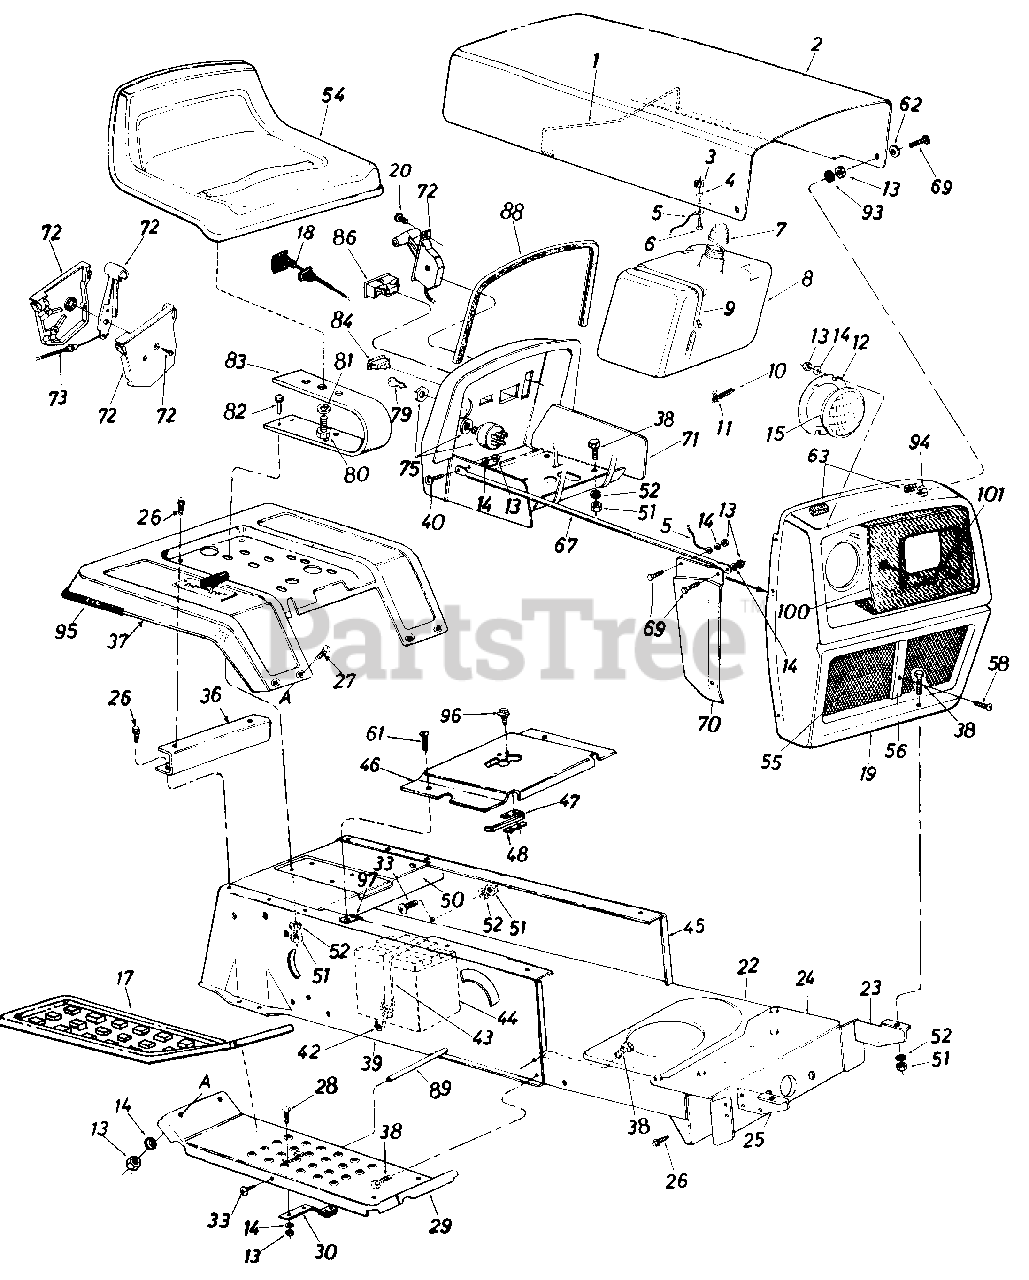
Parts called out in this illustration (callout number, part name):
1	Hood Spring
2	Hood
3	Hex Sems Nut #10-24 Thd.*
5	Hood Stop 7" Lg.
6	Truss Hd. Scr. #10-24 x 1/2"*
7	Fuel Cap Gauge
8	Fuel Tank
9	Tie Strap
10	Fuel Line
11	Hose Clamp
12	Headlight Retainer
13	Hex Nut 1/4-20 Thd.*
14	L-Wash. 1/4" I.D.*
15	Headlight
17	Foot Pad
18	Choke Control 29" Lg.
19	Grille Ass'y.
20	Truss Mach. AB-Tap Scr. #10 x .50" Lg.
22	Lower Frame
23	Grille Mount Brkt.-L.H.
24	Front Pivot Brkt.
25	Grille Mount Brkt.-R.H.
26	Hex Wash. Hd. AB-Tap Scr. 5/16 x .75" Lg.
27	Carriage Bolt 1/4-20 x .50"*
28	Carriage Bolt 1/4-20 x .62"*
29	Running Board
30	Blade Brake Ass'y.
33	Truss Mach. Scr. 5/16-18 x .75" Lg.*
36	Fender Mount Brace
37	Fender
38	Hex Bolt 5/16-18 x .75" Lg.*
39	R.H. Side Frame
40	Hex Bolt 1/4-20 x .62" Lg.*
42	Battery Strap Hook
43	Battery Hold Down Strap
44	12-V Battery
45	L.H. Side Frame
46	Shift Cover
47	Reverse Safety Switch
48	Insulator Nut Plate
50	Hitch Plate
51	Hex Nut 5/16-18 Thd.
52	L-Wash. 5/16" I.D.
54	Seat Ass'y.
55	Seat with Safety Switch
56	Moulding
58	Hex Wash. F-Tap Scr. #8 x .38" Lg.
61	Truss Mach. Tap Scr. #10 x .50" Lg.
62	Fl-Wash. .281 I.D. x .73 O.D.
63	Foam Strip 3/8 x 1-1/8 x 11/2
67	Grille Support Rod
69	Truss Hd. Scr. 1/4-20 x .75"*
70	R.H.-Grille Side Panel
71	Dash Panel Ass'y.
72	Throttle Control Box Ass y.
73	Throttle Control Wire
75	Ignition Switch
79	Ignition Key
80	Hex Bolt 1/2-13 x 1.0" Lg.
81	L-Wash. 1/2" I.D.
82	Hex Bolt 5/16-18 x 1.0"*
83	Seat Spring 5.5" High
84	Light Switch
86	Ammeter
88	Molding Strip 27" Lg.
89	Running Board Rod
93	Rubber Wash. 1/2" I.D. x 1.0 O.D. x .25"
94	Hex Sems Ins. L-Nut 1/4-20 Thd.
95	Trim Strip-81"
96	Hex Wash. Hd. AB-Tap Scr. #8 x .50" Lg.
97	Speed Nut #10Z
100	Bezel
101	Truss Scr. #10-24 x .62" Lg.
